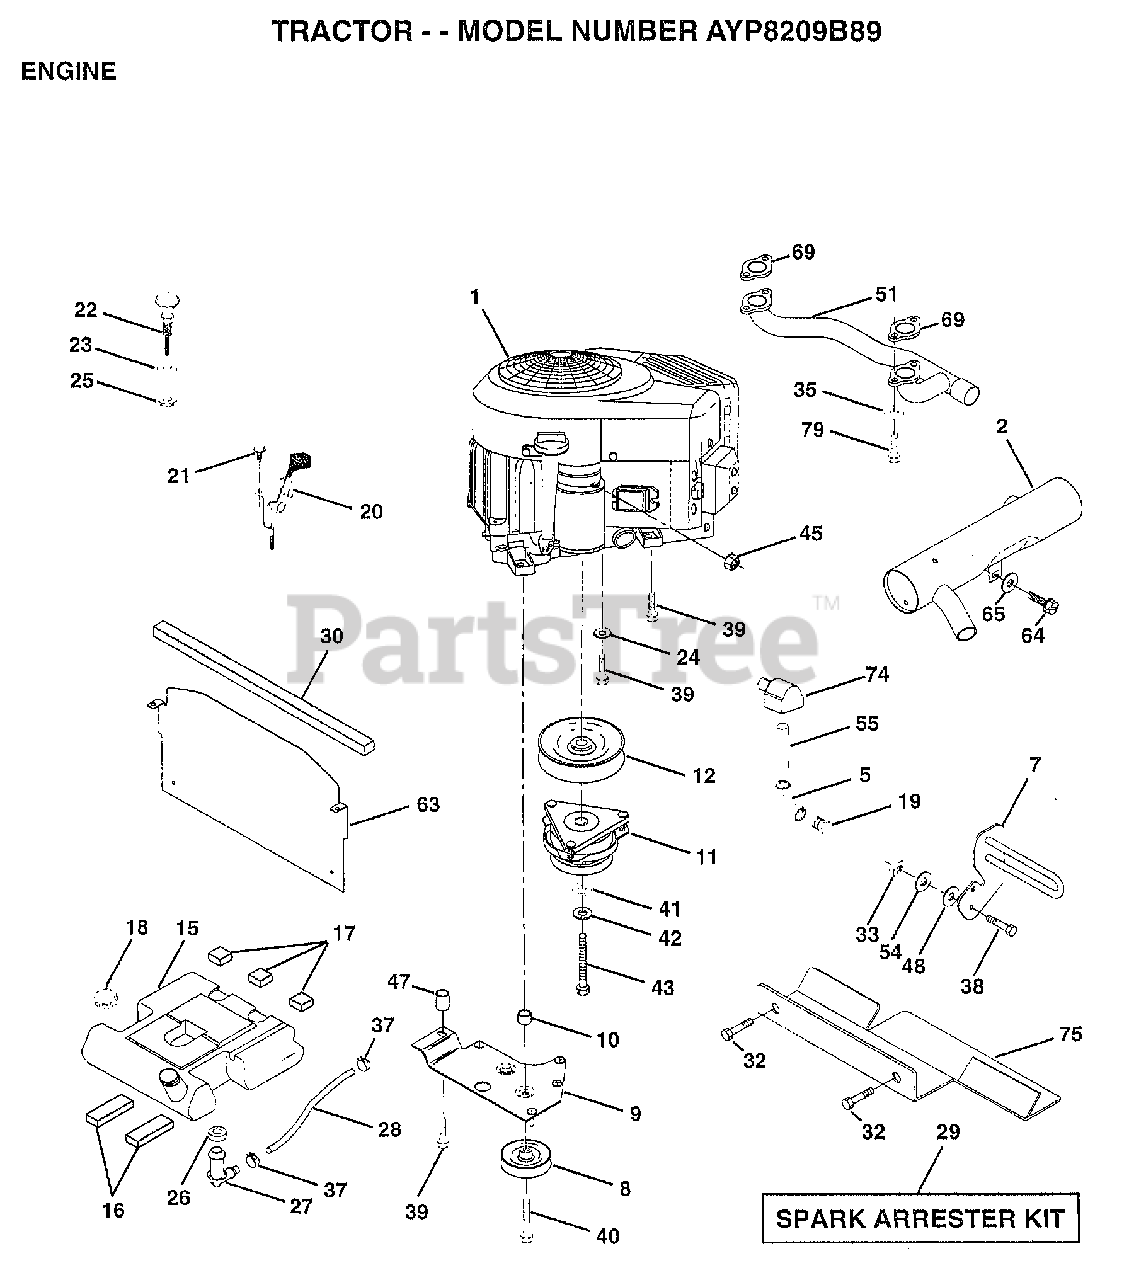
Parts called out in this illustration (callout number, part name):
2	MUFFLER SIDE1-1/8
4	PIPE NIPPLE LT
5	ELBOW
7	GUARD.MUFFLER.ASM
9	KEEPER ASM BELT
10	BUSHING.
12	PULLEY.ENG.CLUTCH
15	TANK FUEL REAR
16	PAD IDLER TI
17	PAD-SPACER LT
18	CAP ASM FUEL
19	PLUG T
21	SCREW LT
22	CHOKE CONTROL
23	WASHER
24	LOCKWASHER
25	"NUT,KEPS 3/8-24IM"
26	BUSHING OUTLET T
27	STEM.TANK.FUEL
29	SPARK ARREST KIT
30	FOAM-STRIP LT
33	NUT
35	LOCKWASHER
37	HOSE CLAMP
38	"BOLT,HEX"
39	SCREW.3/8-16X2.25
40	SCREW.TT.3/8-16X4
41	WASHER
42	LOCKWASHER
43	BOLT.7/16-20X4.25
45	NUT
47	SPACER.ENGINE
48	WASHER T
51	PIPE.MANIFOLD
54	WASHER
63	HEAT.SHIELD.VGT.
64	SCREW
65	WASHER
69	GASKET MUFFLER
74	ELBOW STREET BASS
75	SHIELD.HEAT.INTEK.VGT
79	SCREW
